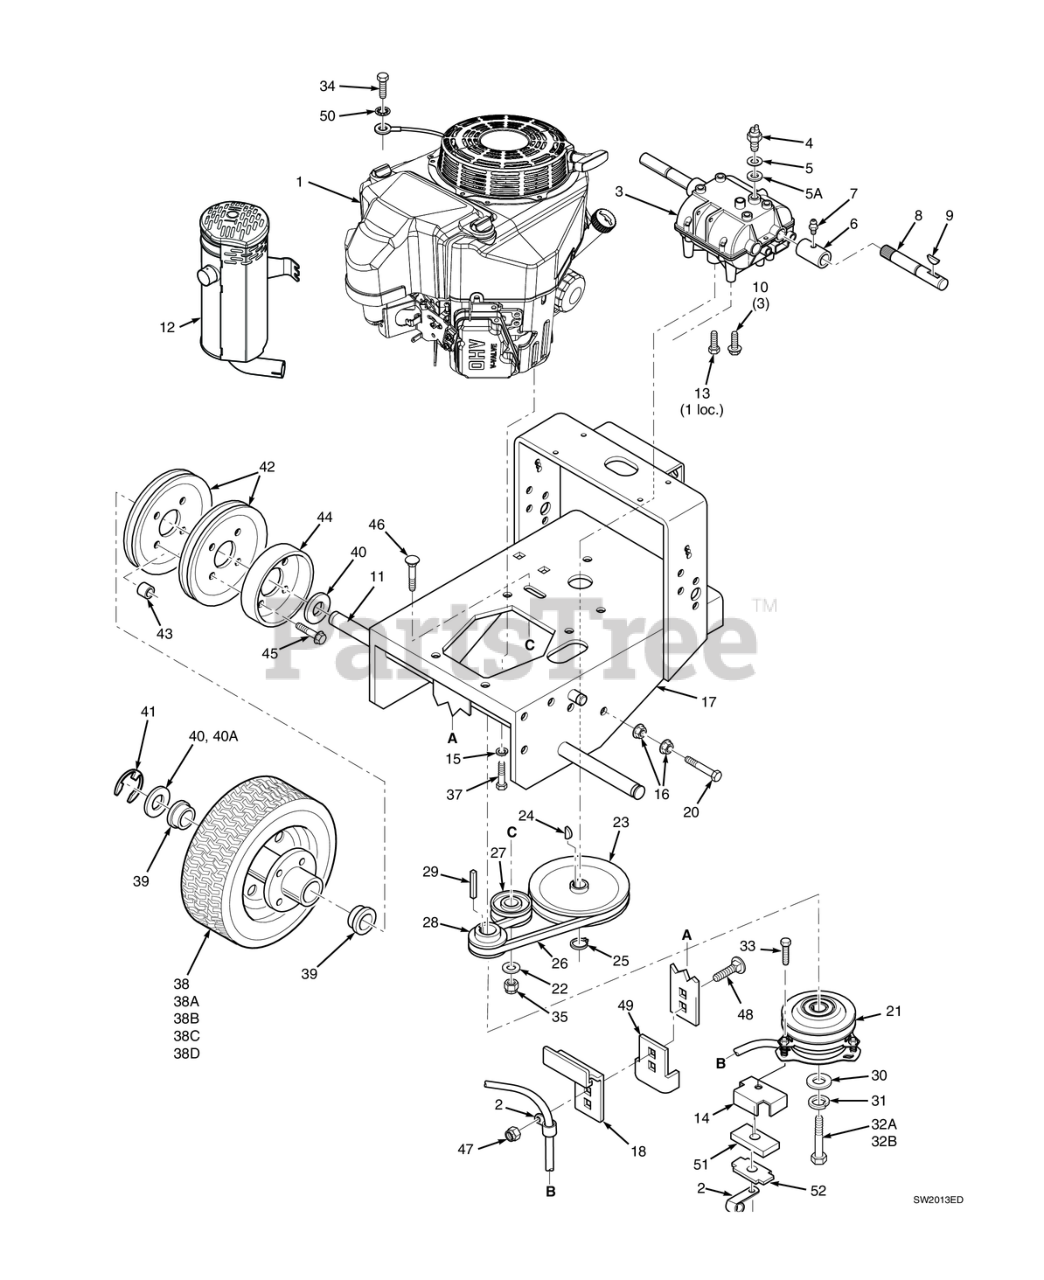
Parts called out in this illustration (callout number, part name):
1	Engine, Kawasaki 14FS (FS481V)
1	Engine, Kawasaki 15FS (FS541V)
2	Clamp, Cable 1/2" I.D.
3	Transmission, 5-speed (Peerless 700-070, 9 tooth spline)
4	SWITCH, TRANSMISSION INTERLOCK N.O.
5	FIBER WASHER - .010
5A	FIBER WASHER - .020
6	Coupler, Jackshaft
7	Greese Fitting, Straight 1/4 - 28
8	Jackshaft (fits SW32,36,48 & 52)
9	KEY, HI PRO #9
10	Capscrew, 5/16-18 x .75 Serrated Flange Hex Head
11	Wheel Axle (SW 32)
12	Muffler, Kawasaki (FS481, FS541, FS600)
13	BOLT, SERRATED FLANGE HEX HEAD 5/16-18 X 3/4"
14	Backing Plate, Clutch Stop
15	Lockwasher, 3/8" Spring, Kawasaki FX / FS
16	NUT, 3/8-16 SERRATED FLANGE HEX HEAD
17	Engine Deck (fits SW32)
18	Plate, Clutch Bracket
19	Nut, Serrated Flange 5/16-18 (Right Front Engine Mounting, Briggs and Kohler Only)
20	Capscrew, Hex Head 3/8-16 x 3-3/4"
21	Clutch, Electric (Ogura)
22	Flatwasher, 3/8" Special (.391 x .938 x .105)
23	PULLEY, TRANSMISSION INPUT
24	KEY, WOODRUFF #9, 3/16 X 3/4"
25	RETAINING RING, 5/8 EXT. - BASIC
26	BELT, TRANSMISSION DRIVE
27	Pulley, Idler 3" Dia. - 52"
28	Pulley, Traction Drive
29	KEY, 1/4 X 1/4 X 3/4"
30	Flatwasher, 7/16-.469 x 1.75 x .25 (48, 52)
31	Lockwasher, 7/16� Spring
32A	Bolt, Hex Head 7/16-20 x 2-1/2" (Kohler)
32B	Cpsrw, M10-1.5 x 55 Metric Hex Hd
33	Bolt, Hex Head 5/16-18 x 1-1/2" - Front
34	Bolt, Hex Head M8 - 1.25 x 16 (48V / 52V)
35	HEX NUT, ELASTIC STOP LOCK, 3/8-16
36	Flatwasher, 5/16-.375 x .875 x .083 (35BV & 37BV-EFI)
37	Bolt, Hex Head 3/8-16 x 1-1/4"
38	WHEEL ASSEMBLY(INCL. 38C-38D)(FITS SW32)
38B	Rim & Bearing Assembly (fits SW36, 48, 52)
38C	Tire, 13 x 5.00-6 2-ply (SW32 only)
38D	Rim Assembly (incl. 39) (SW32 only)
39	Wheel Brng. NWC (OD 1.984 - 1.980)
40	Flatwasher, 1" (1.062 x 1.75 x .10)
40A	Flatwasher, 1" (1.062 x 1.50 x .048")
41	Ring, Retaining 1" External "E"
42	PULLEY, WHEEL DRIVE
43	SPACER, WHEEL PULLEY
44	BRAKE DRUM
45	Bolt, Serrated Flange Hex Head 5/16-18 x 1.50"
46	SHORT SQUARE NECK CARRIAGE BOLT, 3/8-16 X 2"
47	HEX NUT, ELASTIC STOP LOCK, 5/16-18
48	Bolt, Carriage 5/16-18x1" (large frame units only)
49	Plate, Clutch Anti-Rotation
50	Lockwasher, 5/16" Ext. Tooth (Kohler x1)
51	Rubber Pad, Clutch Stop
52	Plate, backing Clutch Pad
